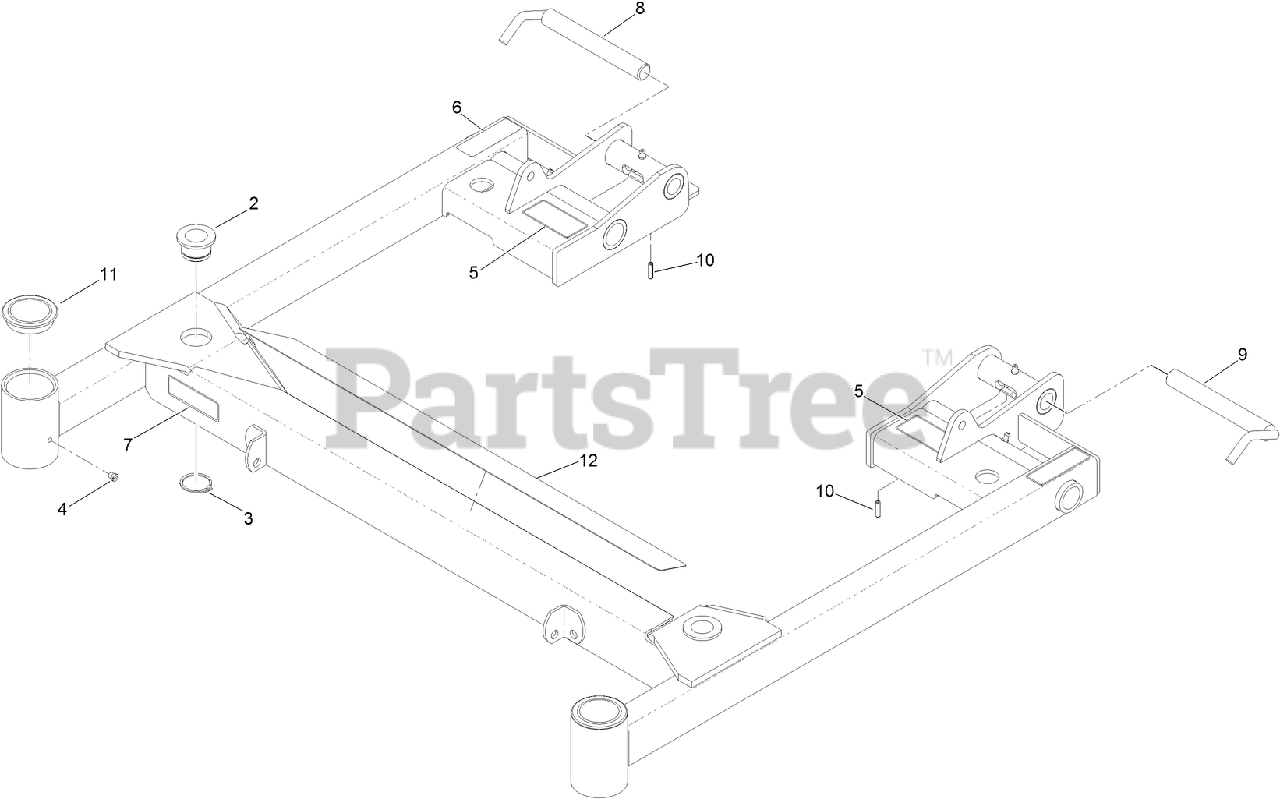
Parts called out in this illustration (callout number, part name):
2	BUSHING-SUPPORT, DECK
3	RING-RETAINING
5	DECAL-SPRING
6	DECAL-FOLDING DECK
7	DECAL-DANGER
8	LOCK-DECK, RH
9	LOCK-DECK, LH
10	PIN-SPRING
11	CAP-GREASE
12	PAD-ANTI SKID
